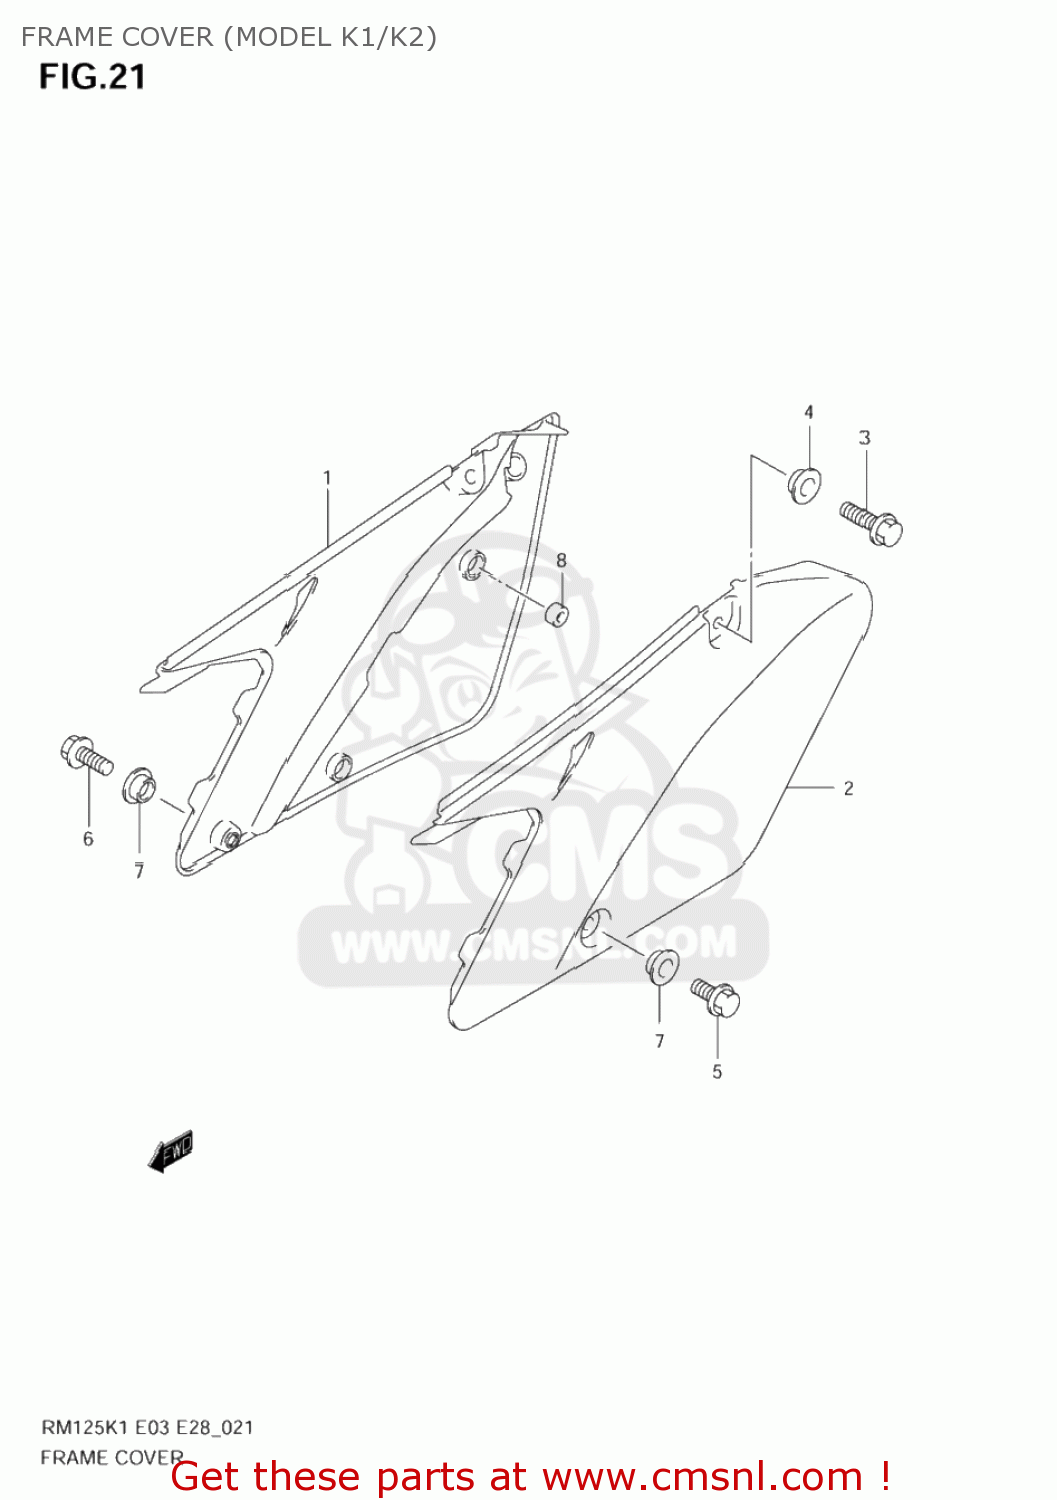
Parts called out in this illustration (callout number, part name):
1	DEKSEL.FRAME R
2	COVER,FRAME,L
3	BOLT
4	WASHER,FRAME C
5	BOLT
6	BOLT
7	WASHER
8	CUSHION,FRAME COVER,R
